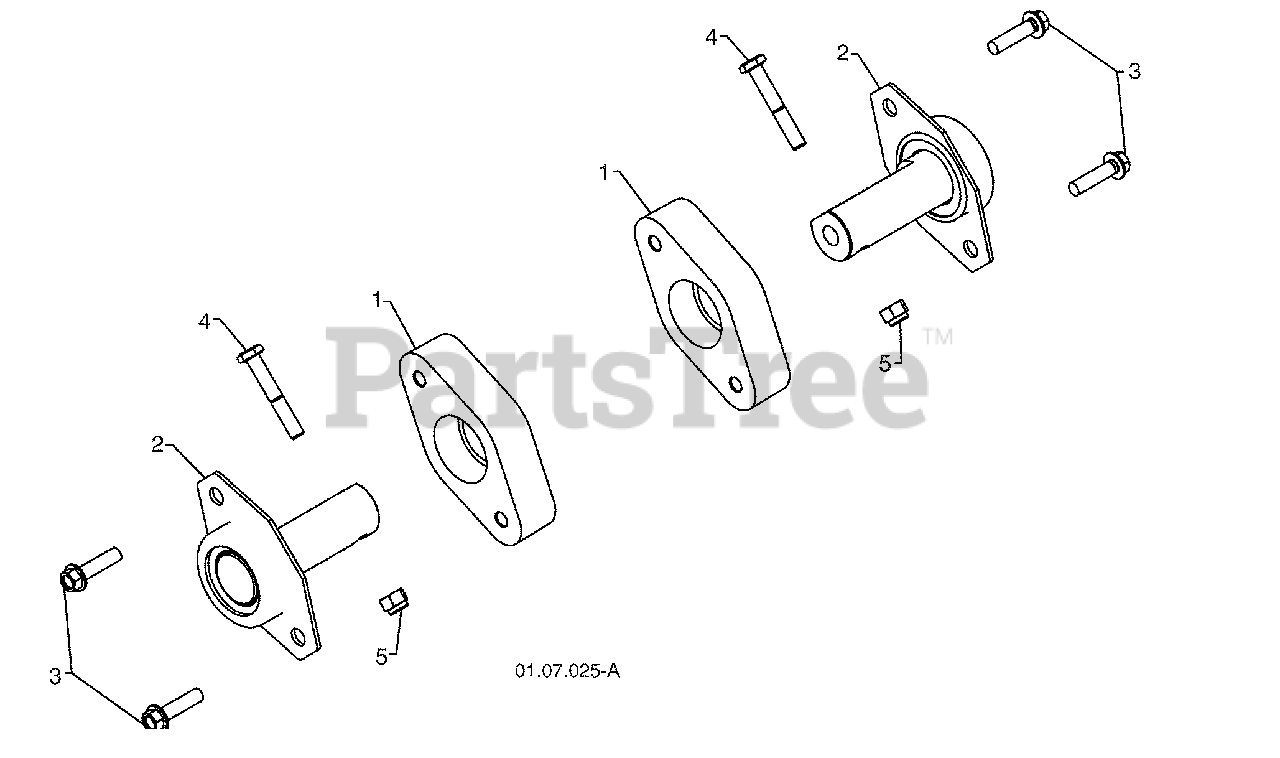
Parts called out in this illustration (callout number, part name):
1	PLASTIC RETAINER
2	AUGER BALL BEARING
3	SCREW 5/16-18 x 1.00
4	SCREW 1/4-20 x .625
5	NUT 1/4-20
